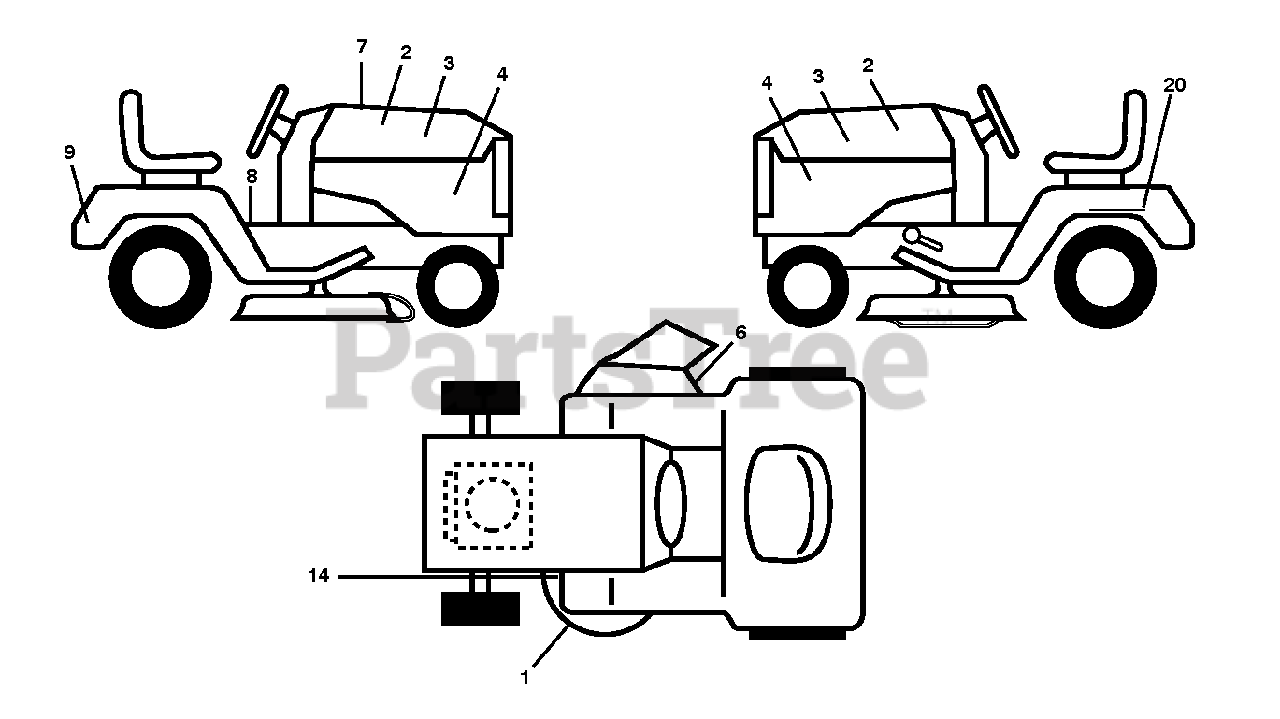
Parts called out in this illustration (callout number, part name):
1	DECAL V BELT SCHEMATIC
2	DECAL.WARNING.CUST.RESP.E85.
3	RP.DECAL.BADGE.170MM.TEXTLOGO
4	DECAL.SIDE.PANEL.YTA19K42
6	DECAL.WARN.KEEP.HAND.AWAY
8	DECAL.FENDER.WARNING
9	DECAL.FENDER
14	DECAL V BELT SCHEMATIC
20	DECAL BTRY SYMBOLS
